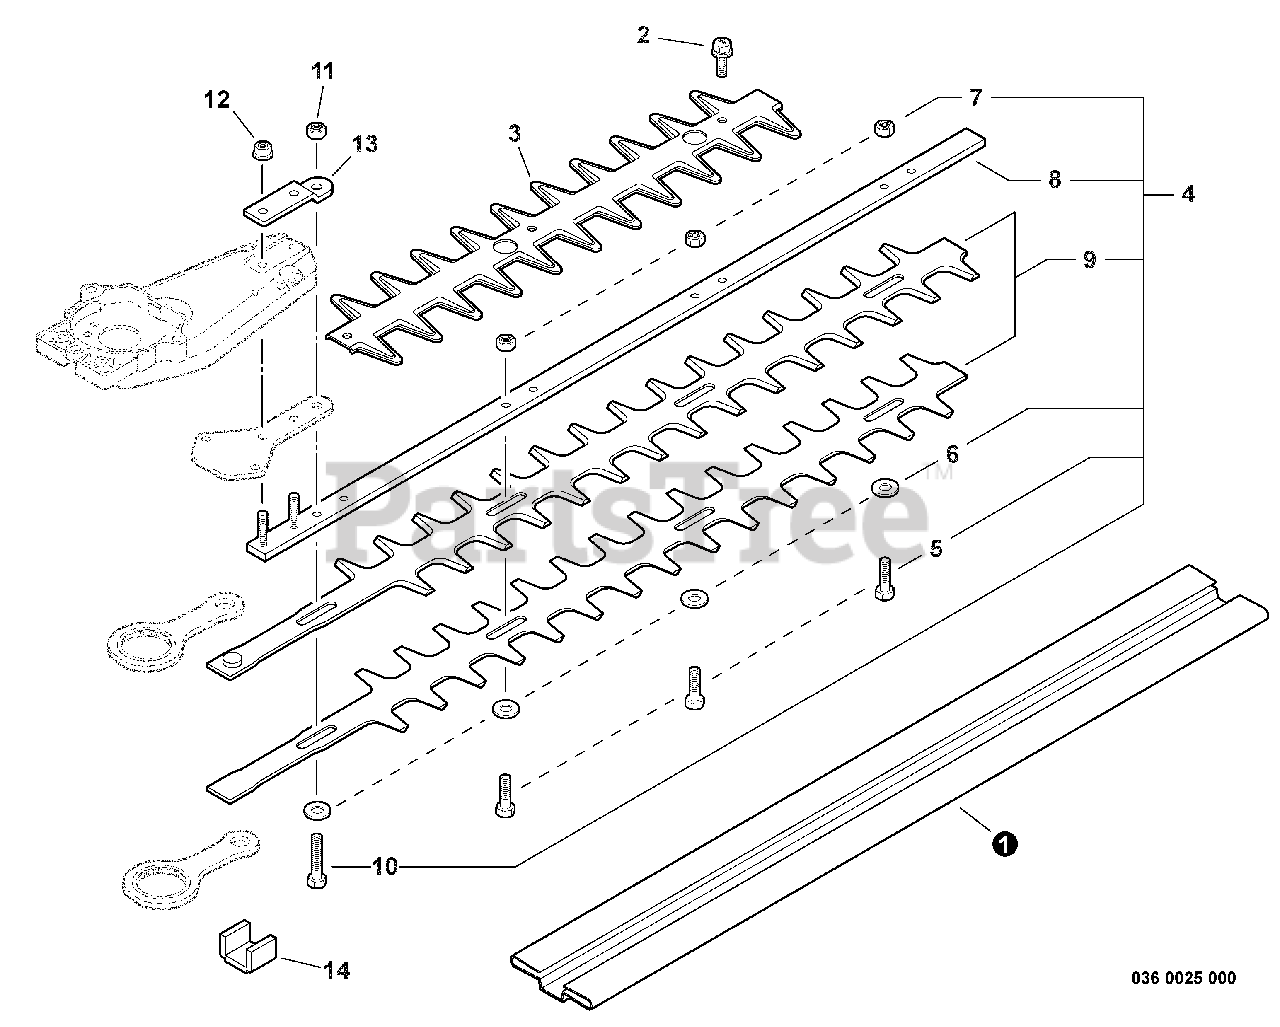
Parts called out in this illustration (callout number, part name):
1	SCABBARD 24"
2	BOLT M5×8
3	GUARD, CUTTER BLADE
4	CUTTER ASSY, 24"
5	BOLT M6×20
6	WASHER M6
7	NUT, LOCK M6
8	GUIDE BAR, 24"
9	BLADE, 24"
11	NUT, LOCK M6
12	NUT, FLANGE M5
13	BRACKET, CUTTER
14	PACKING, FELT
